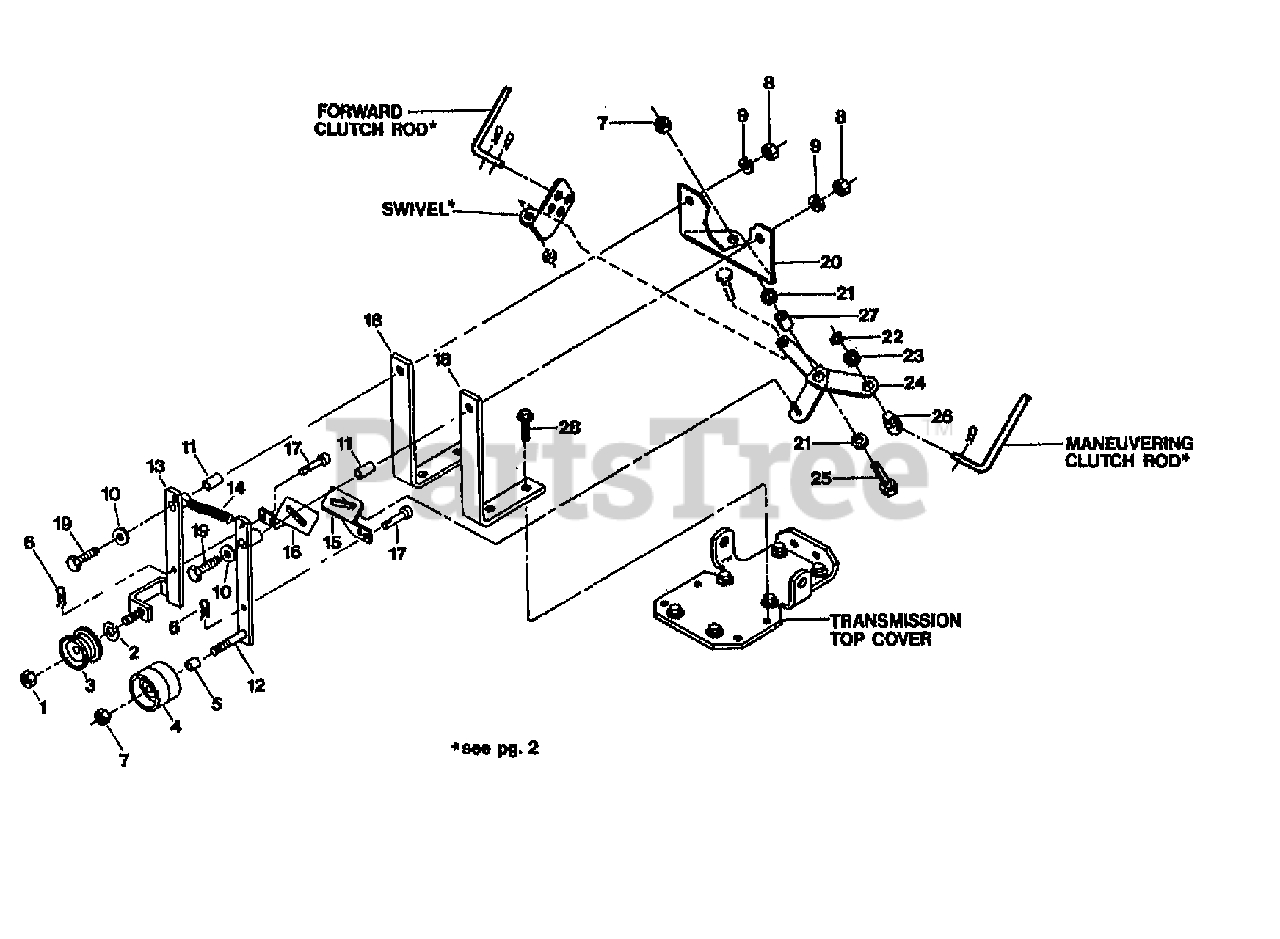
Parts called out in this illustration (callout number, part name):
1	NUT-LOCK 3/8-16 NYLON ZP
2	BUSHING-.54X.38X.08
3	IDLER-REV
4	PULLEY-FWD IDLER
5	BUSHING-.5X.375X.3
6	PIN-CLIP .08
7	NUT-H/LK 3/8-16
8	NUT-HEX 5/16-18 ZP
9	WASHER-LK .312 ZP
10	WASHER-#.75X.32X.09 ZP
11	BUSHING-.438X.323X.712
12	ARM-IDLER FWD PNT
13	IDLER-REV
14	SPRING-.436 X 3.25
15	LINK-FWD
17	PIN-CLEVIS .375X.719 ZP
18	MOUNT BAR-PNT (20691)
19	SCR-HH 5/16-18X2.25 G5ZP
20	SHIFT BASE-OPC PNT
21	SPACER-.88X.385X.09 ZP
22	RING-KLIP .500 ZINC
23	WASHER-#.88X.51X.063 ZP
24	BELLCRANK-OPC PNT
25	SCR-HH 3/8-16X1.25
26	PIVOT-ROD
27	BUSHING-.5X.38X.4
28	SCR-HFLK 5/16-18X1.00 ZP
